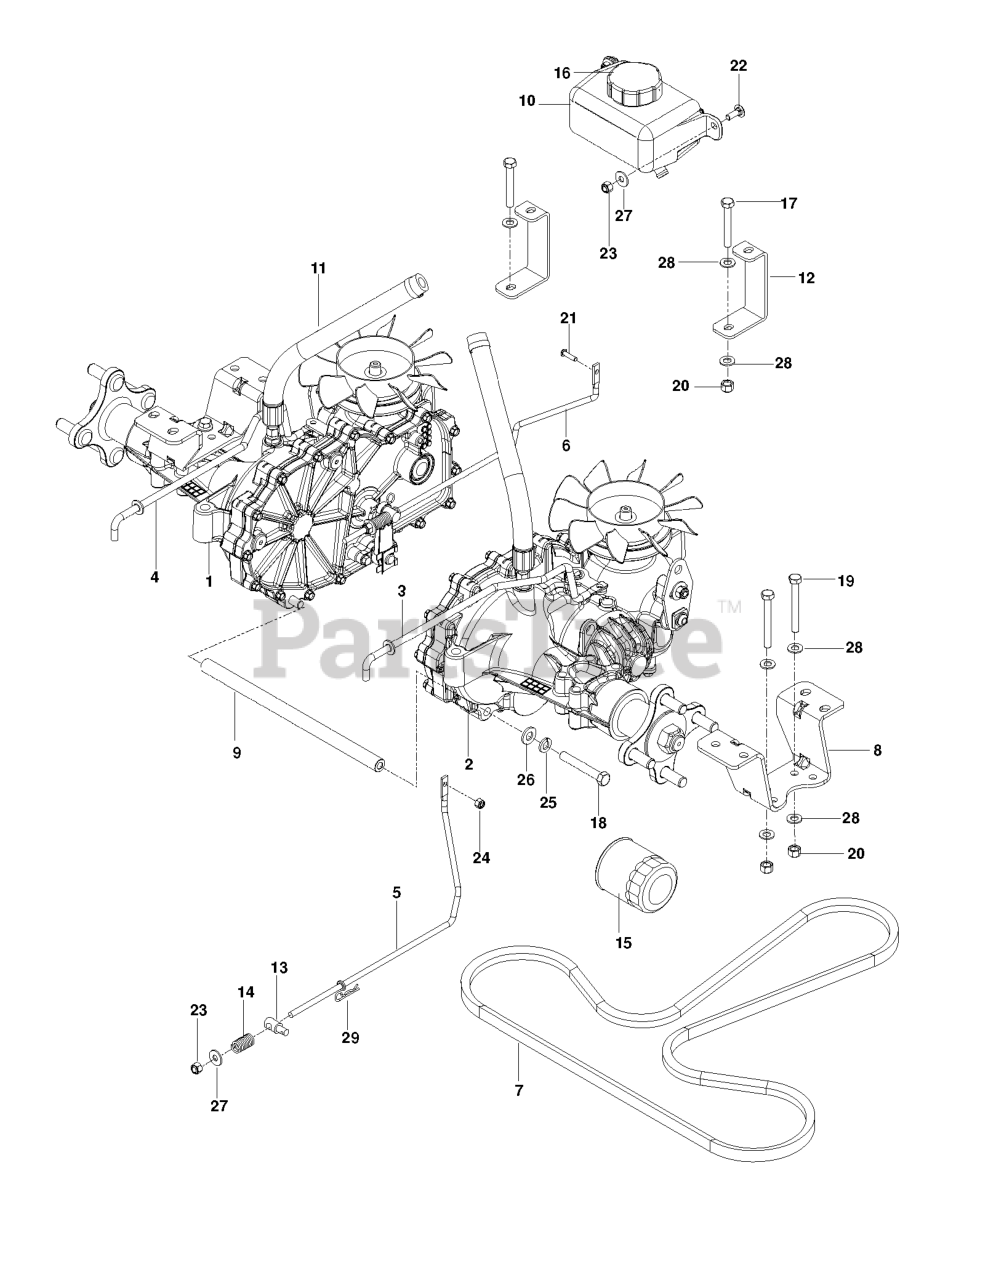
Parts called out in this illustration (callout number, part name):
1	HG_TRANS, ZT-2800 RT
2	HG_TRANS, ZT-2800 LEFT
3	ROD, BYPASS, RT
4	ROD, BYPASS, LT
5	LINKAGE, BRAKE RT
6	LINKAGE.BRAKE.LT
7	BELT, EZT HYDRO
8	EZT MOUNT, REAR, BLACK
9	SPACER TUBE, EZT, 11.08
10	HG_EXPANSION TANK W/CAP 71354
12	SUPPORT.FRONT.TRANS.BLACK.
13	BRAKE SWIVEL
15	HG_FILTER, ZT4800 52114
16	HG_CAP 52375
18	HCS 3/8C X 2 1/2
19	HCS 5/16C X 2-3/4
20	NUT 5/16 NYLOC
21	SCR #10-24 X 3/4
22	RHSNB 1/4C X 3/4
23	NUT.1/4-20.HEX.NYLOC.ZD
24	NUT 10-24 NYLOC
25	SLW 3/8 STD
26	WASHER 3/8 SAE FLAT
27	WASHER 1/4 FLAT
28	FLAT WASHER 5/16 SAE
29	HAIRPIN #2
